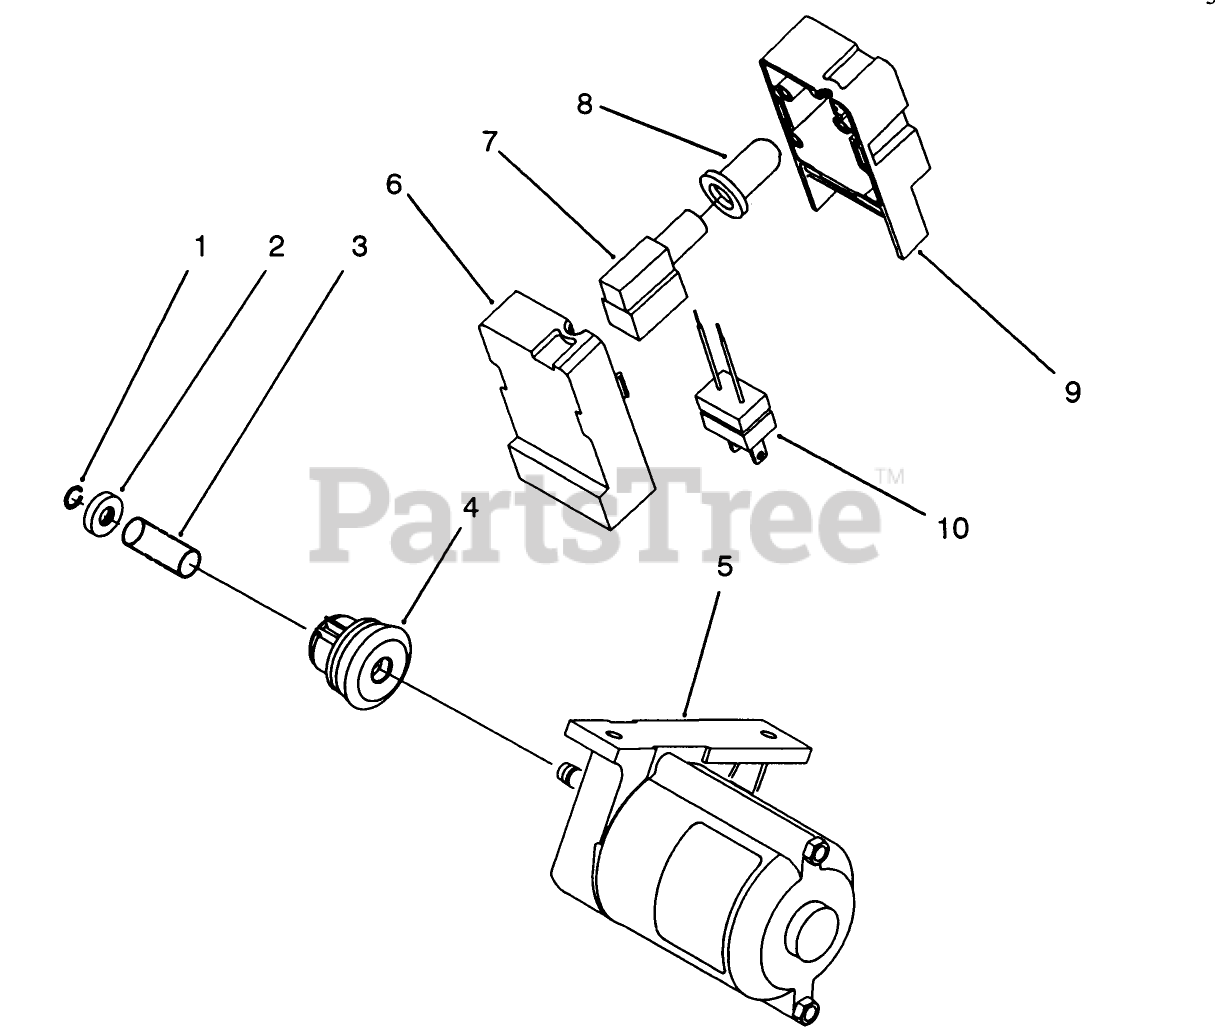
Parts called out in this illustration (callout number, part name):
1	RING-LOCK
2	PINION STOP
3	SPRING
4	ORDER BRIGGS 801293
7	SWITCH-STARTER
8	BOOT-SWITCH
